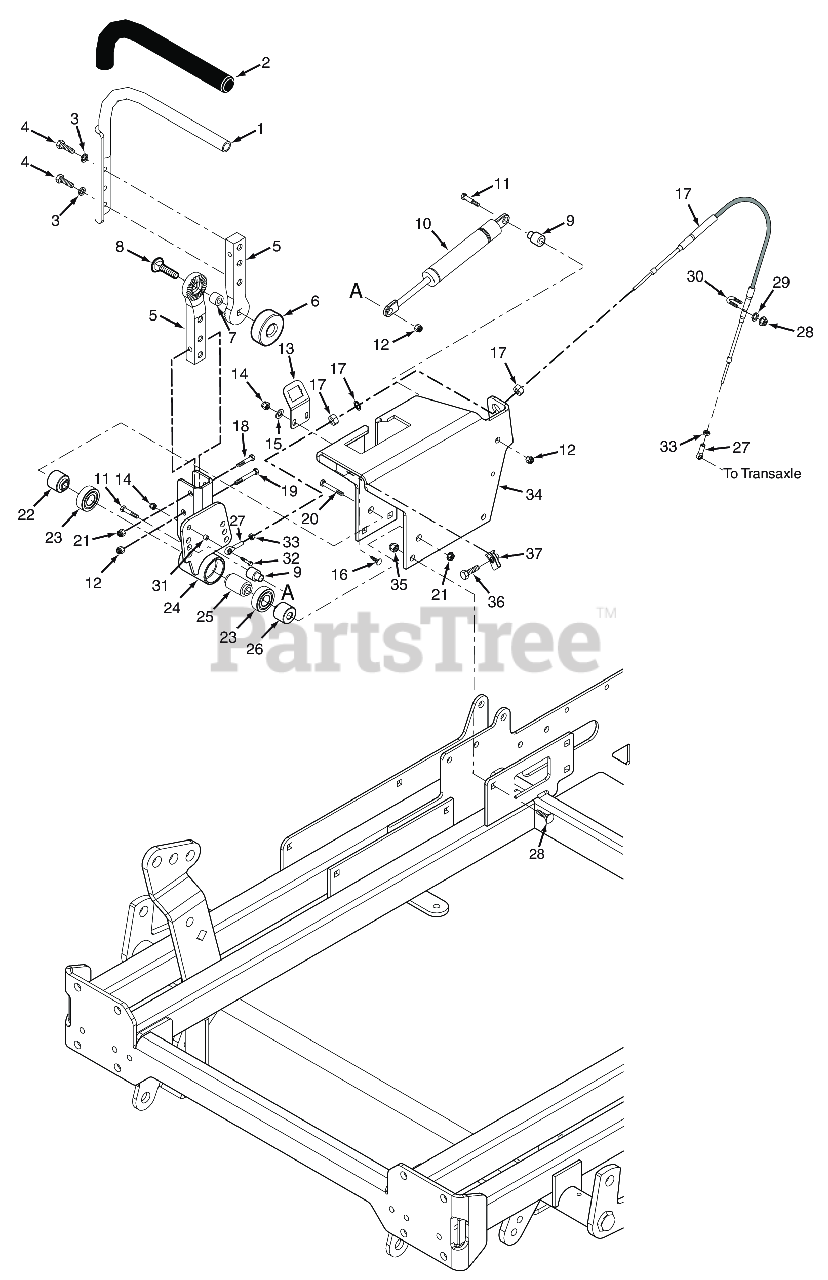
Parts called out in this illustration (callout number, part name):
1	Handle Bar w/Grip - LH
1	Handle Bar w/Grip - RH
2	Grip, Control Handle
3	Lockwasher, 5/16 (.317 x .586 x .078) Helical Spring
4	Bolt, Heax Head 5/16-18 x 1" (48V / 52V)
5	Pivot, Control Lever
6	Knob, Control Handle
7	Spacer, Rubber
8	Bolt, RDHD Carr. 3/8-16 x 1-1/2 (52" & 61")
9	Spacer, Pump Dampener
10	Damper, Steering
11	Bolt, Hex Head 5/16-18 x 2-1/2" (x3) (35BV & 37BV-EFI)
12	HEX NUT, ELASTIC STOP LOCK, 5/16-18
13	Bracket, Operator Presence Switch
14	HEX, NUT, ELASTIC STOP LOCK, 1/4-20
15	Flatwasher, 1/4" (.312 x .750 x .065")
16	Serr. Fl. Hex Head CPSCR, 1/4-20 x 3/4"
17	Control Cable, Hydro
18	Bolt, Hex Head 5/16-18 x 2-1/2" (x3) (35BV & 37BV-EFI)
19	Bolt, Hex Head 5/16-18 x 2-1/2" (x3) (35BV & 37BV-EFI)
20	Bolt, 3/8-16 x 6.00" Hex Head
21	HEX NUT, ELASTIC STOP LOCK, 3/8-16
22	Spacer, Controls
23	BEARINGS, BALL, NEUTRAL RETURN
24	Pivot Weldment, Control Arm LH
24	Pivot Weldment, Control Arm RH
25	Spacer, Bearing
26	Spacer, Controls
27	Rod End, 1/4-28 RH Thread
28	Nut, Jam 5/16-24 UNF-2B
29	Lockwasher, 5/16 (.317 x .586 x .078) Helical Spring
30	U-Bolt, 5/16-24
31	Spacer
32	SERR. FLG. HEX HEAD CAPSCREW, 5/16-18 X 3/4
33	Nut, Jam 1/4-28 UNF
34	Bracket Weldment, Control Lever RH w/Decal
34	Bracket Weldment, Control Lever LH w/Decal
35	Nut, Serrated Flange 5/16-18 (Right Front Engine Mounting, Briggs and Kohler Only)
36	Bolt, Hex Head 3/8-16 x 2" Special Lock
37	U-Nut, 3/8-16 (short)
